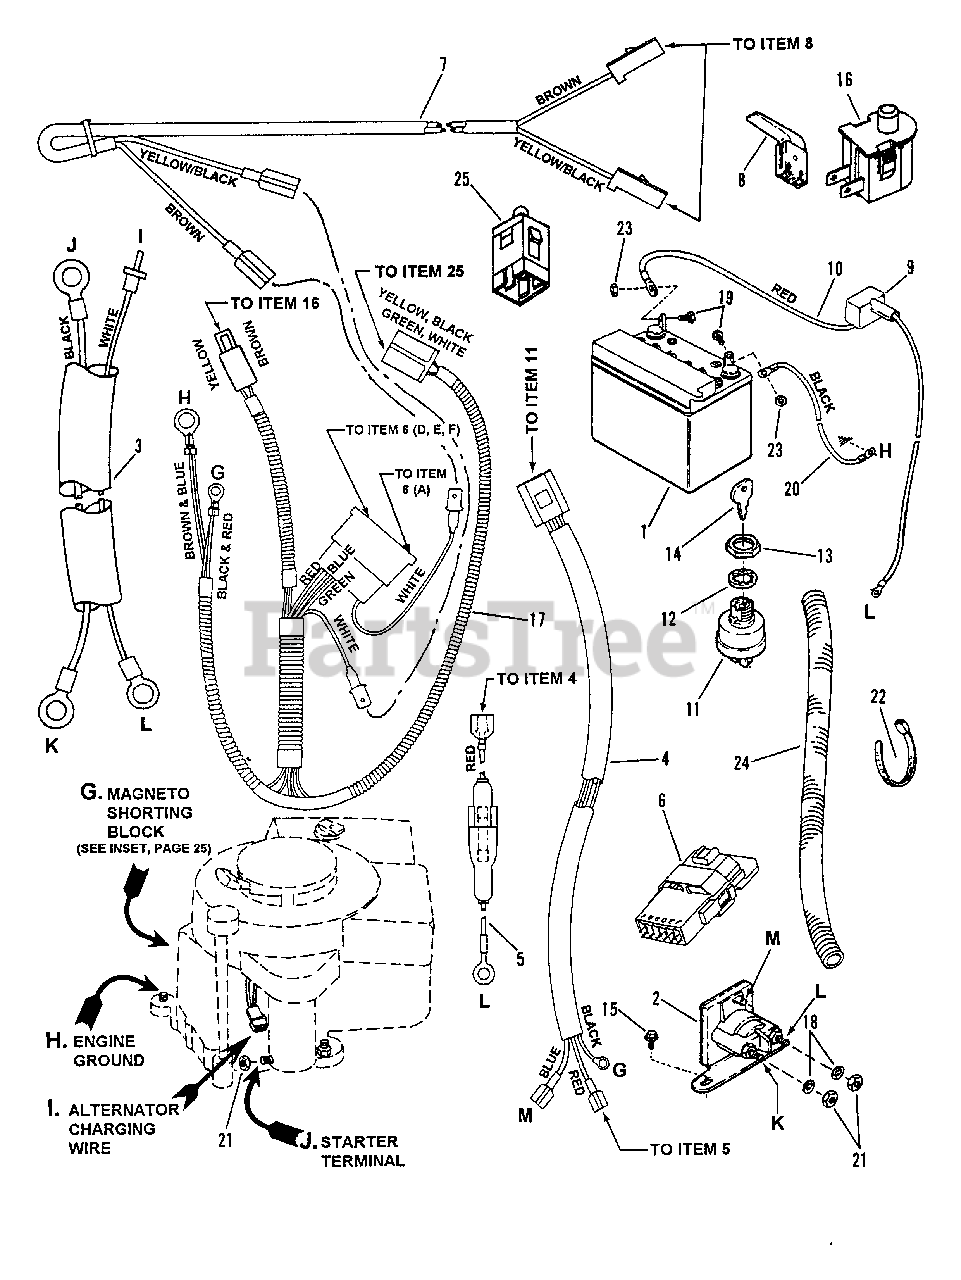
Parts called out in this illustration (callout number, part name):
1	KIT, 12V Dry Charge Battery
2	SOLENOID
3	HARNESS, Starter Wiring (Briggs)
4	HARNESS, Ignition Wiring (Briggs)
5	HOLDER, Fuse
6	INTERLOCK Module (Briggs)
7	HARNESS, Deck Interlock Wiring
8	SWITCH, Deck Interlock
9	COVER, Battery Cable
10	CABLE, Positive (Red)
11	SWITCH, Ignition (ncludes keys #11138)
12	WASHER, 5/8 Internal Tooth Lock
13	NUT, 5/8-32 Hex
14	KEY, Switch
15	SCREW, 1/4-20 x 1/2" Self-Tapping
16	SWITCH
17	HARNESS WIRE
18	WASHER,1/4 Internal Tooth Lock
19	SCREW, 1/4-20 x 5/8" Hex Head Cap
20	CABLE, Negative
21	NUT, 1/4-20 Hex
22	TIE, 7" Long Cable
23	NUT,1/4-20 Hex Lock
24	CONDUIT
25	SWITCH, Traction
